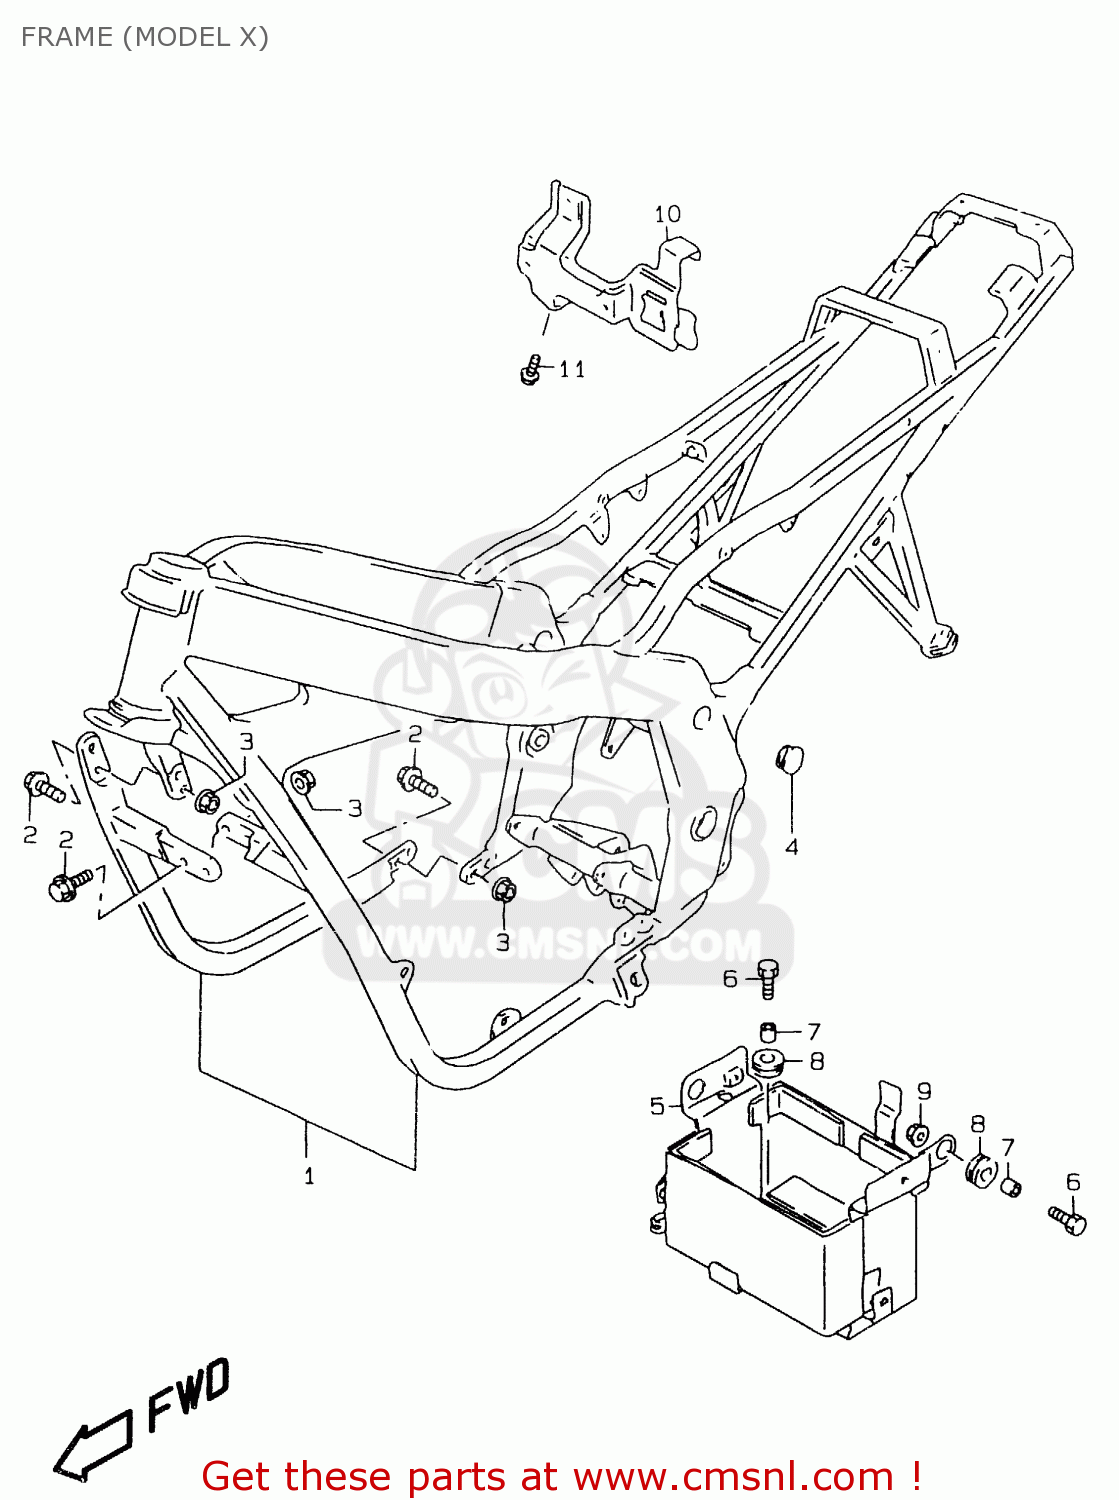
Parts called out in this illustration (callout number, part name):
1	FRAME SET
2	BOLT
3	NUT
4	CAP,BODY FRAME
5	HOLDER,BATTERY
6	BOLT(6X20)
7	SPACER(6.1X9X7.5)
8	CUSHION
9	NUT
10	HOLDER,ELECTRIC PARTS
11	BOLT
